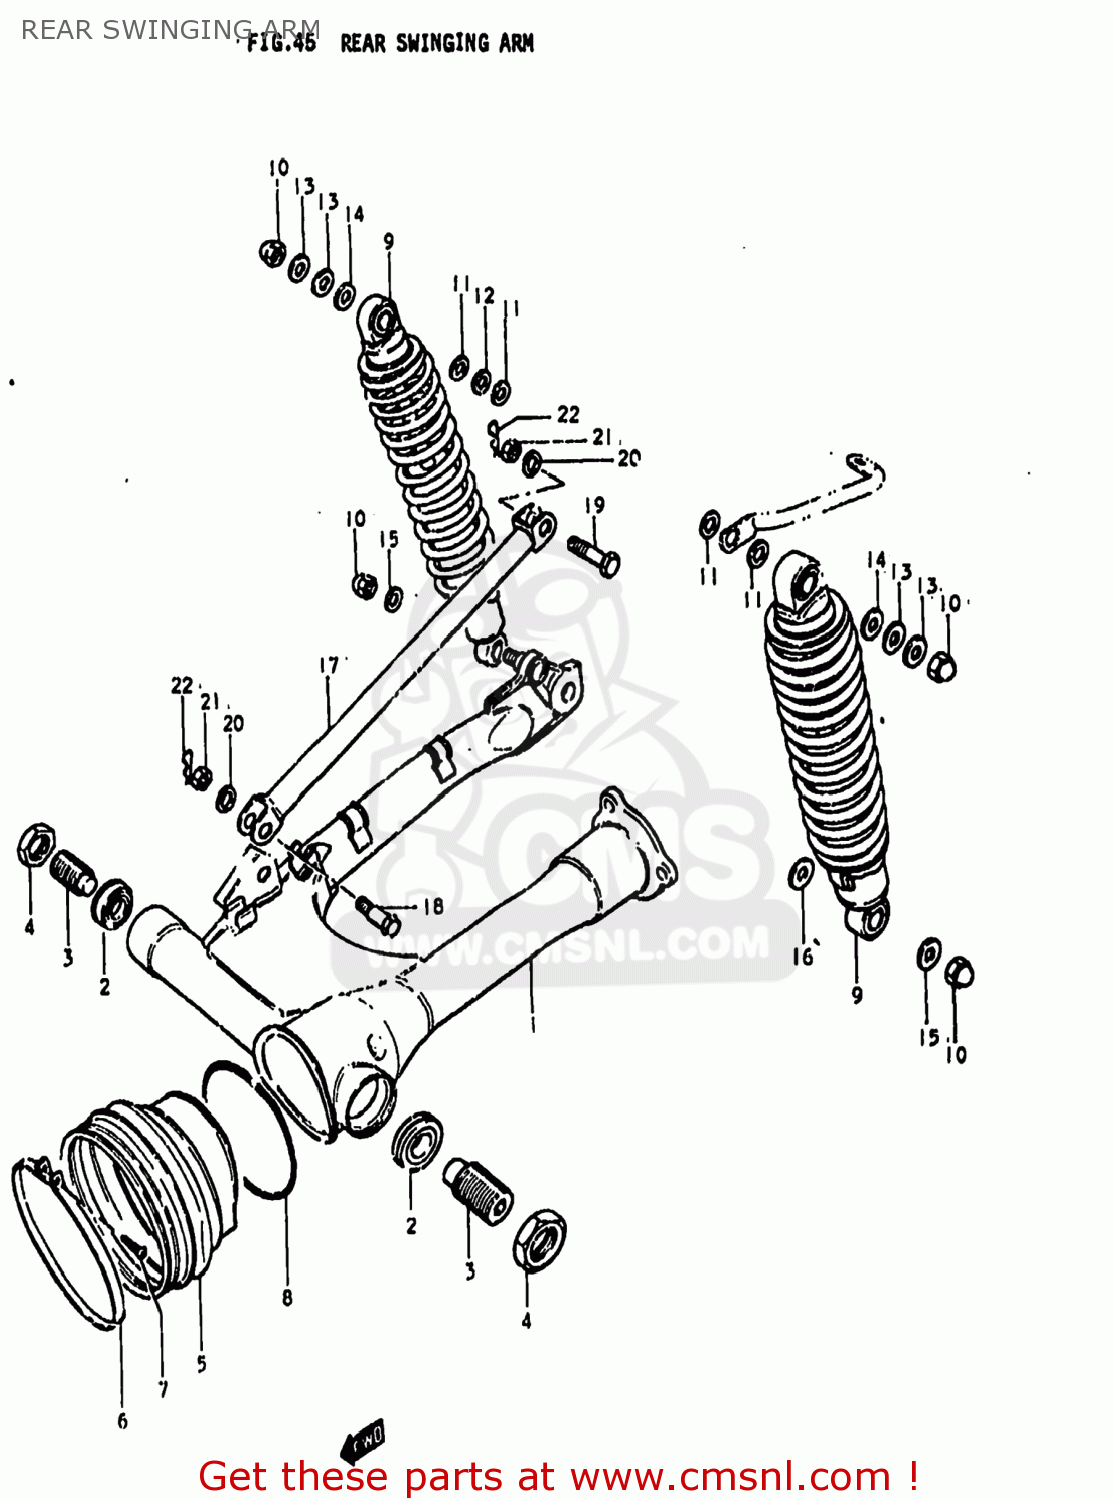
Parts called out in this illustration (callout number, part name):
1	SWING ARM ASSEMBLY,REAR
2	BEARING(17X40X13.25)
3	BOLT,REAR SWING ARM PIVOT
4	NUT
5	BOOT,PROPELLER SHAFT
6	CLAMP
7	SCREW 4X25
8	SPRING,PROPELLER SHAFT
9	ABSORBER ASSEMBLY,REAR SHOCK
10	NUT, LOWER LH
11	WASHER
12	WASHER (12.5X24X3.2)
13	WASHER
14	WASHER(10.5X24X3.2)
15	WASHER
16	WASHER
17	LINK,REAR TORQUE
18	BOLT
19	BOLT 10X40
20	LOCK WASHER
21	NUT
22	CLIP
